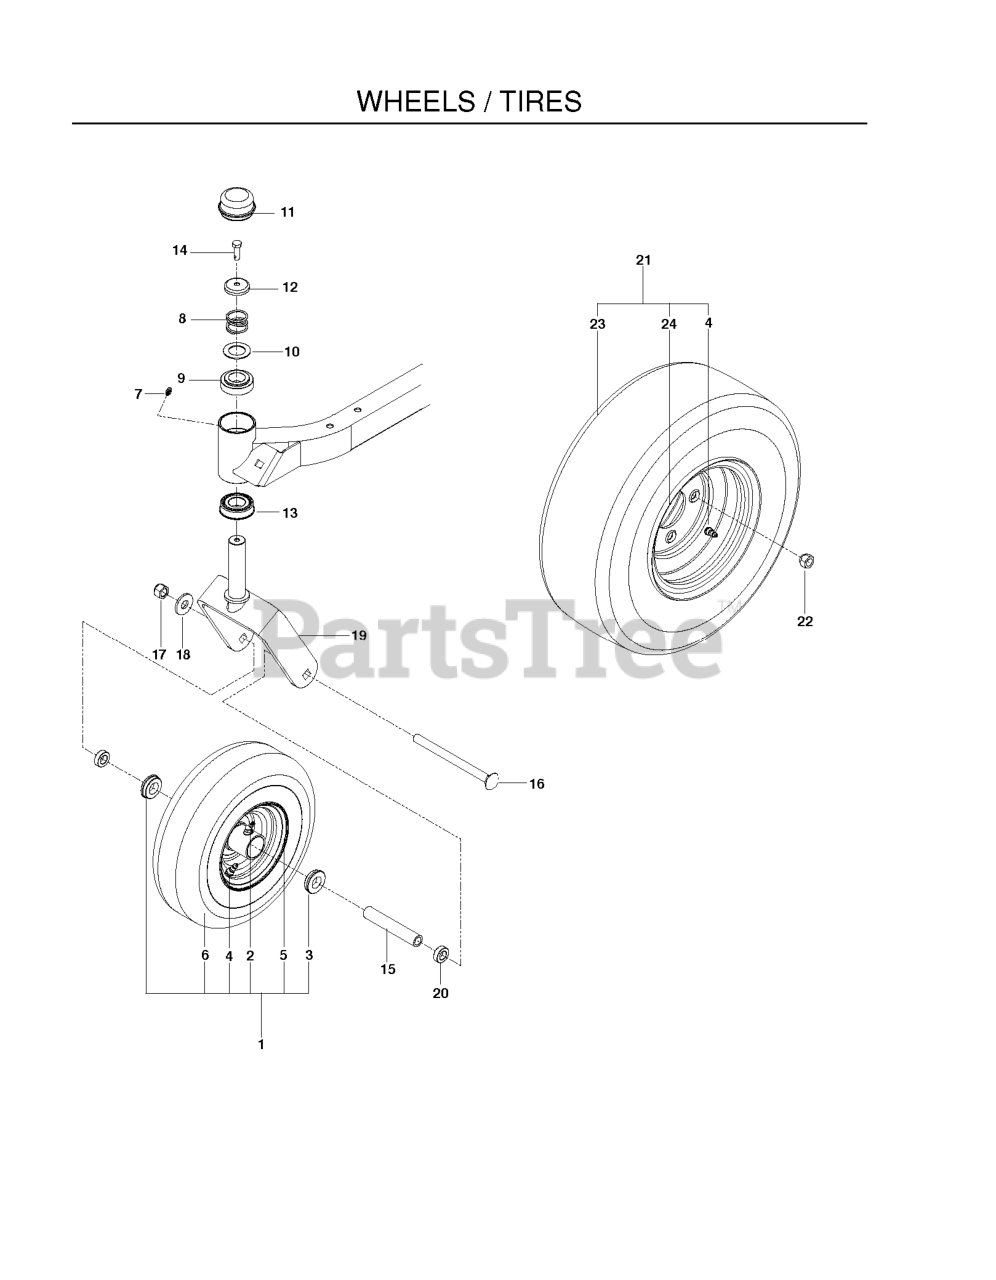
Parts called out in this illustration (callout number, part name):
1	TIRE.CASTER.ASSEM.11X4-5.GR
2	ZERK
3	BUSHING, WHEEL, 3/4"
4	VALVE STEM TR-412
6	TIRE.11"X4"-5.4PLY.SMOOTH.KEND
7	ZERK, 3/16, DRIVE IN
8	SPRING, CASTER
9	BUSHING, CASTER
10	WASHER, 1.025 ID X 1.64
11	GREASE CAP
12	CASTER.PLUG
13	BEARING FLANGED
14	5/16-18X1 HHB G5W/NY
16	RHSNB 1/2-13 X 6.50 GR2 ZD
17	NUT 1/2-13 HEX CNTRLK GR 5 ZD
18	WASH USS FLAT 1/2
19	YOKE.CASTER.ORANGE
20	SPACER, 5/16"
21	WHEEL ASSY REAR 18 X 7.5-8
22	LUG NUT 1/2F
23	TIRE.KENDA.18X7.5-8.4PLY
24	RIM 5.375"X8"
